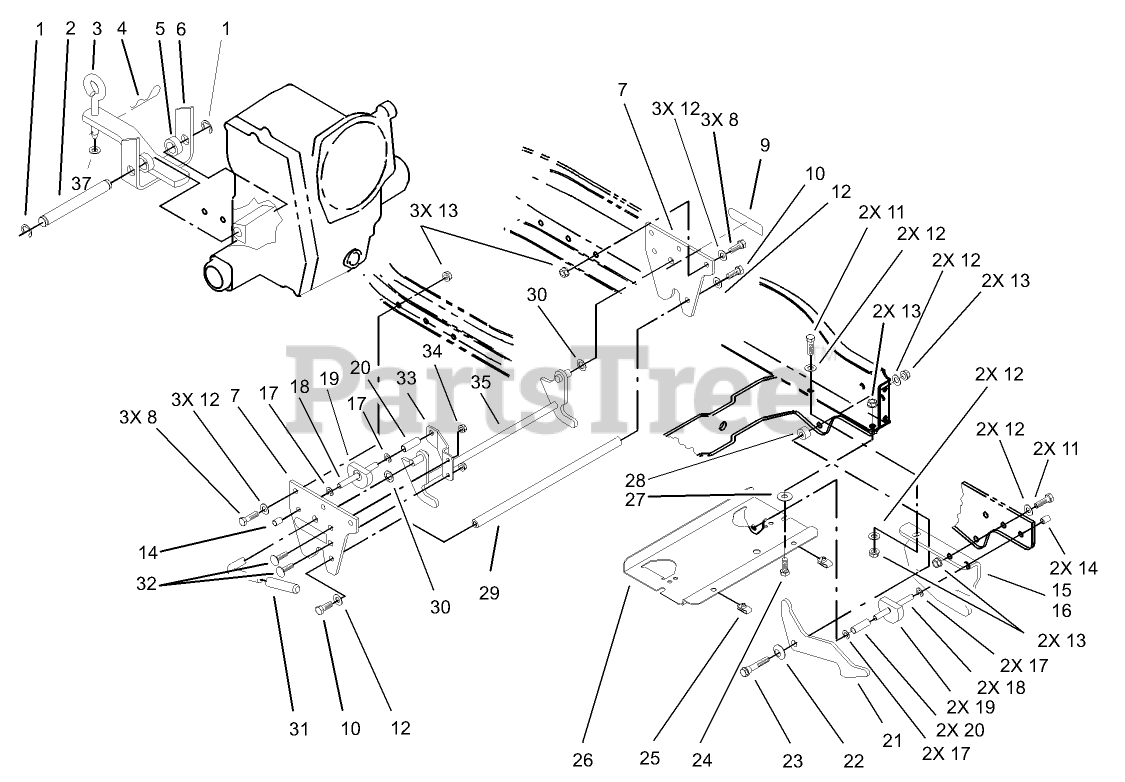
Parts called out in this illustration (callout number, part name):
1	E-RING
2	PIN-STATIONARY HITCH
3	PIN-TOOL
4	PIN-HAIR
5	SPACER
7	PLATE-HITCH
8	SCREW-HH
9	DECAL-ATTACH A MATIC
10	SCREW-HH, LOCK
11	SCREW-HH
12	WASHER-FLAT
13	NUT-LOCK, NI
14	CAP-ROD, PLUNGER
15	HANGER-RH
16	HANGER-LH
17	RING-RETAINING
18	ROD-LOCK
19	LOCK-LATCH
20	SPRING
21	LATCH-BOX, PULLEY
22	WASHER-SPRING
23	BOLT-SHOULDER
24	SCREW-HH
26	TRAY-BATTERY
27	WASHER-TOP THRUST
28	SPACER
29	ROD-SPACER
30	WASHER
31	GRIP
32	BOLT-CARR
33	BRACKET-ARM, MID
34	NUT-LOCK, NI
37	WASHER-FLAT
